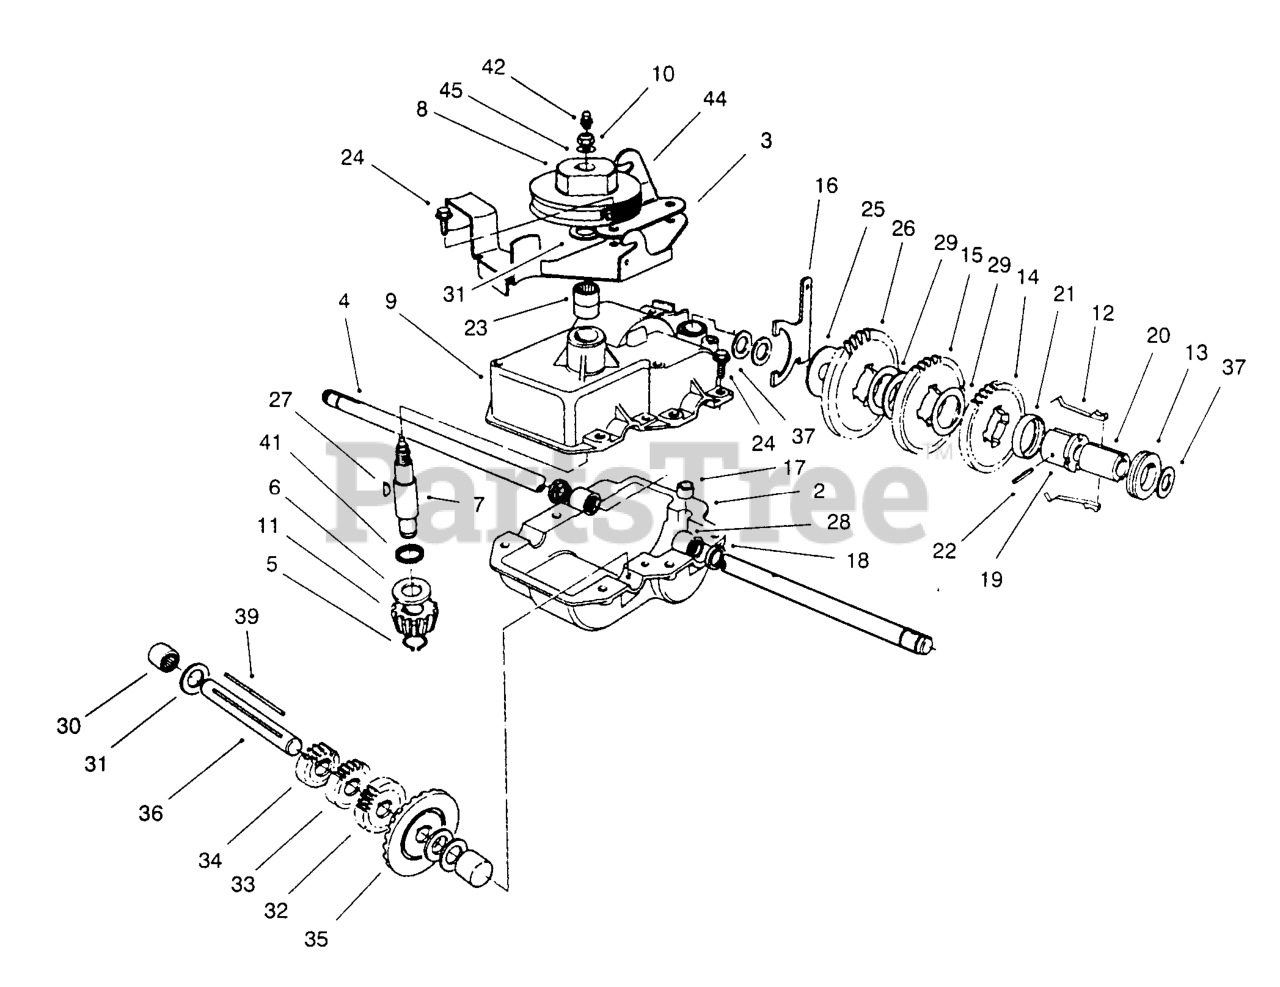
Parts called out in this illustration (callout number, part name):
3	BRACKET-GUIDE, BELT
4	SHAFT-OUTPUT
5	RING-RETAINING
6	WASHER-THRUST
10	NUT-HEX
11	PINION-BEVEL
12	KEY-SHIFT
13	COLLAR-SHIFT
14	GEAR-38T
15	GEAR-42T
16	YOKE-SHIFT
17	BUSHING-YOKE
18	SEAL-OIL
19	SLEEVE-GEAR
21	RETAINER-KEY
22	PIN-GROOVE
23	BEARING-NEEDLE
24	SCREW-HWHTF
27	KEY-WOODRUFF
30	BEARING-NEEDLE, CLOSED
31	WASHER-THRUST
32	GEAR-18T
33	GEAR-14T
34	GEAR-12T
35	GEAR-BEVEL
36	SHAFT-INTERMEDIATE
37	WASHER-PLAIN
42	FITTING-GREASE, ZERK
44	BRACKET-ENGAGE, TRACTION
45	WASHER-FLAT
